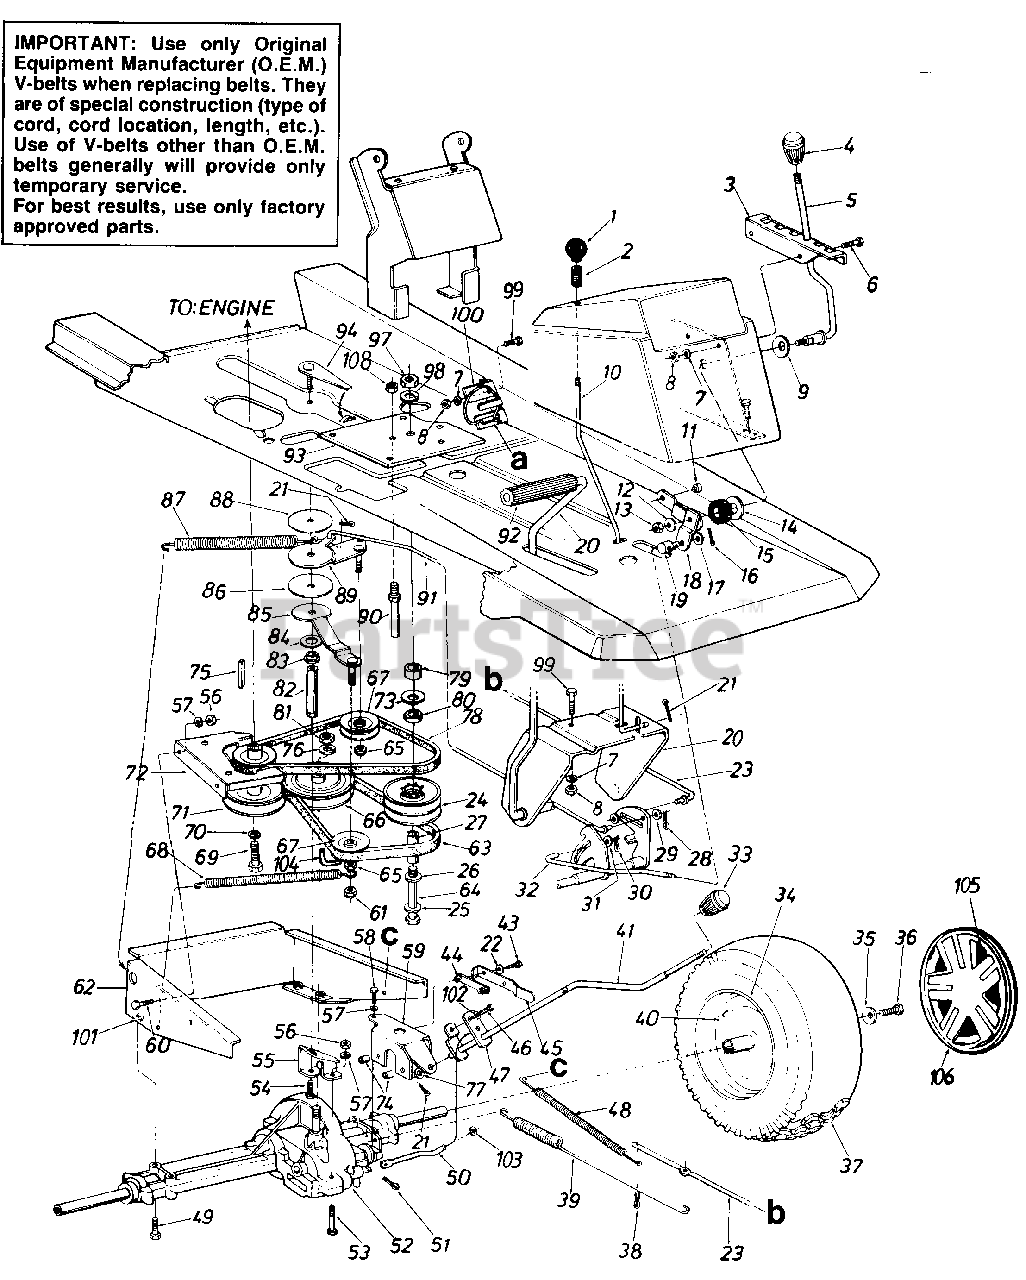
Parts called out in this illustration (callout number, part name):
1	Ball Knob 1/4-20 Thd. 1.25"
2	Compression Spring
5	Speed Control Lever
6	Truss Mach. Scr. 5/16-18 x .75" Lg.
7	L-Wash. 5/16" I.D.
8	Hex Nut 5/16-18 Thd.
9	Bell-Wash. .345" I.D. x .88"
10	Brake Locking Rod
12	Bell-Wash. .345" I.D. x .08"
13	Hex Cent. L-Nut 5/16-18 Thd.
14	Fl-Wash. .50" I.D. x 1.5" O.D.
15	Rubber Washer
16	Intern. Cotter Pin 1/2" Dia.
17	Fl-Wash. .34" I.D. x .68" O.D.
18	Speed Control Lever Brkt. Ass'y.
19	Ferrule-Engagement
20	Clutch/Brake Pedal Ass'y.
21	Cotter Pin 3/32" Dia. x .75"
22	Plastic Washer
24	Variable Speed Pulley Ass'y.
25	Fl-Wash. .4" I.D. x 1.25" O.D.
26	Thrust Brg. 1.25" O.D. x .56" I.D
27	Spacer Sleeve 2.71"
28	Cotter Pin 1/8" Dia. x 1.25"
29	Fl-Wash. .34" I.D. x .60" O.D.
30	Intern. Cot-Pin 5/16" Dia.
31	Fl-Wash. .34" I.D. x .60" O.D.
32	Speed Control Rod
33	Shift Knob
35	Bell-Wash. .345" I.D. x .88"
36	Hex L-Bolt 5/16-24 x .75" Lg.
38	Cotter Pin 1/8" Dia. x 1.25"
39	Extension Spring 17.0" Lg.
40	Air Valve
44	Insulator Nut
45	Spring Switch
46	Hex Bolt 1/4-20 x .50" Lg.
47	Shift Lever Adjusting Link
48	Ext. Spring 81/4" Lg.
49	Hex Bolt 5/16-18 x 2.5" Lg.
51	Intern. Cotter Pin
52	Transaxle
53	Hex Bolt 1/4-20 x 1.75" Lg.*
54	Hex Bolt 3/8-24 x .75" Lg.
57	L-Wash. 1/4" I.D.
58	Self-Tap Mach. Scr. Type 'C"1/4-20 x 1.37" Lg.
59	Shift Lever Support Brkt.
60	Hex Bolt 1/4-20 x 1.00" Lg.
61	Hex L-Nut 3/8-24 Thd.
64	Hex Bolt 3/8-16 x 4.5" Lg.
65	Hex Ins. L-Nut 3/8-24 Thd.
66	V-Pulley
67	V-Belt Idler .38" I.D. x 3.06"
68	Ext. Spring .50" O.D. x 6.37"
69	Hex Bolt 7/16-20 x 1.00" Lg.
70	L-Wash. 7/16" I.D.
71	Engine Pulley
72	Upper Eng. Belt Guard
73	Bell-Wash. .4" I.D. x 1.12" O.D.
74	Spacer.256" I.D. x .50" O.D.
75	Sq.-Key 1/4" x 2.00" Lg.
76	L-Wash. 1/2" I.D.
77	Fl-Wash. .469" I.D. x .88" O.D.
78	V-Belt
79	Spacer 1.00" x .380" O.D.
80	Thrust Wash. .56" I.D. x 1.25" O.D.
81	Hex Nut 1/2-13 Thd.*
83	Flange Bearing .378
84	Fl-Wash. .640" I.D. x 1.24"
85	Idler Bracket Ass'y.
86	Thrust Wash. .635" I.D.
87	Extension Spring 7.58" Lg.
88	Thrust Wash. .385" I.D.
89	Idler Bracket Ass'y. For Clutch
90	Belt Guard Pin 3/8-16 x 2.75" Lg.
92	Foot Pad
98	L-Wash. 3/8 Heavy Duty
99	Hex Bolt 5/16-18 x .75" Lg.
100	Speed Control Rod Brkt.
101	Hex Sems Nut 5/16-18 Thd.
102	Bell-Wash. .265" I.D. x .75" O.D.
103	Push On Retaining Ring
105	Spring Clip
106	Hub Cap
108	Hex Top L-Jam Nut 3/8-16 Thd.
